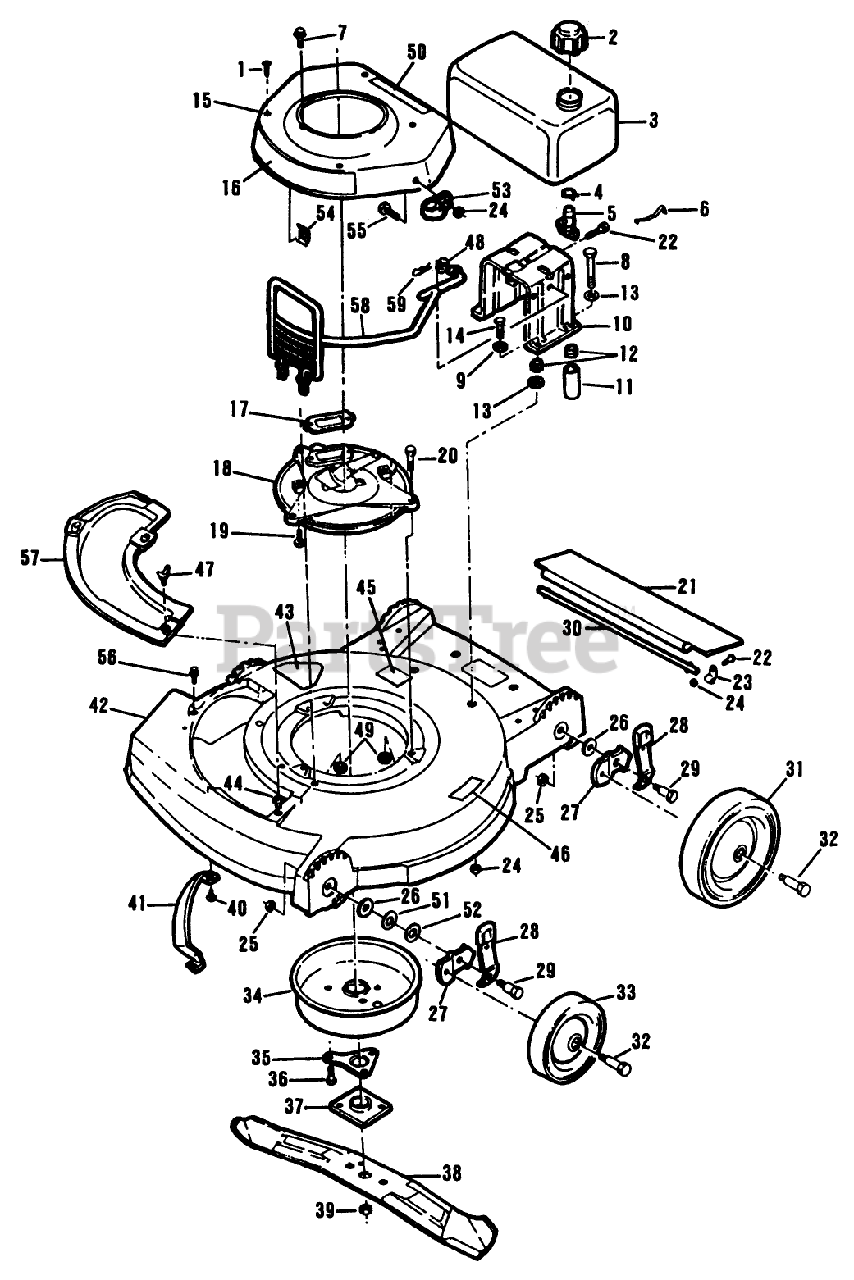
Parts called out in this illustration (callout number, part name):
1	SCREW - SELF TAPPING
2	FUEL CAP & INSERT
4	CLAMP - HOSE S
5	VALVE&SCREEN SM
6	SPRING
7	SCREW SEMS SM
9	WASHER
13	WASHER
14	BOLT PIONEER
18	PLATE F
19	SCREW V
20	SCREW-HH
21	T/SHIELD GEAUGA
23	CLAMP ROD KMC
24	LOCKNUT E
25	LOCKNUT
26	WASHER
28	SPRING ARM ASM
29	BOLT
30	ROD 21" ADVANCE
31	WHL & TIRE AY
32	BOLT-SHOULDER
33	WHEEL & TIRE ASSY
34	MUFFLER COVER F
35	SUPPORT F
36	SCREW
37	PLATE AND COLLAR ASM
39	NUT-BLADE
41	BAR-TOE
42	HOUSING AY-21"
47	WING SCREW LAWRE
48	WASHER SPRING LAR
49	NUT-LOCK F
51	WASHER
52	WASHER
54	PUSHNUT F
59	HAIR PIN
